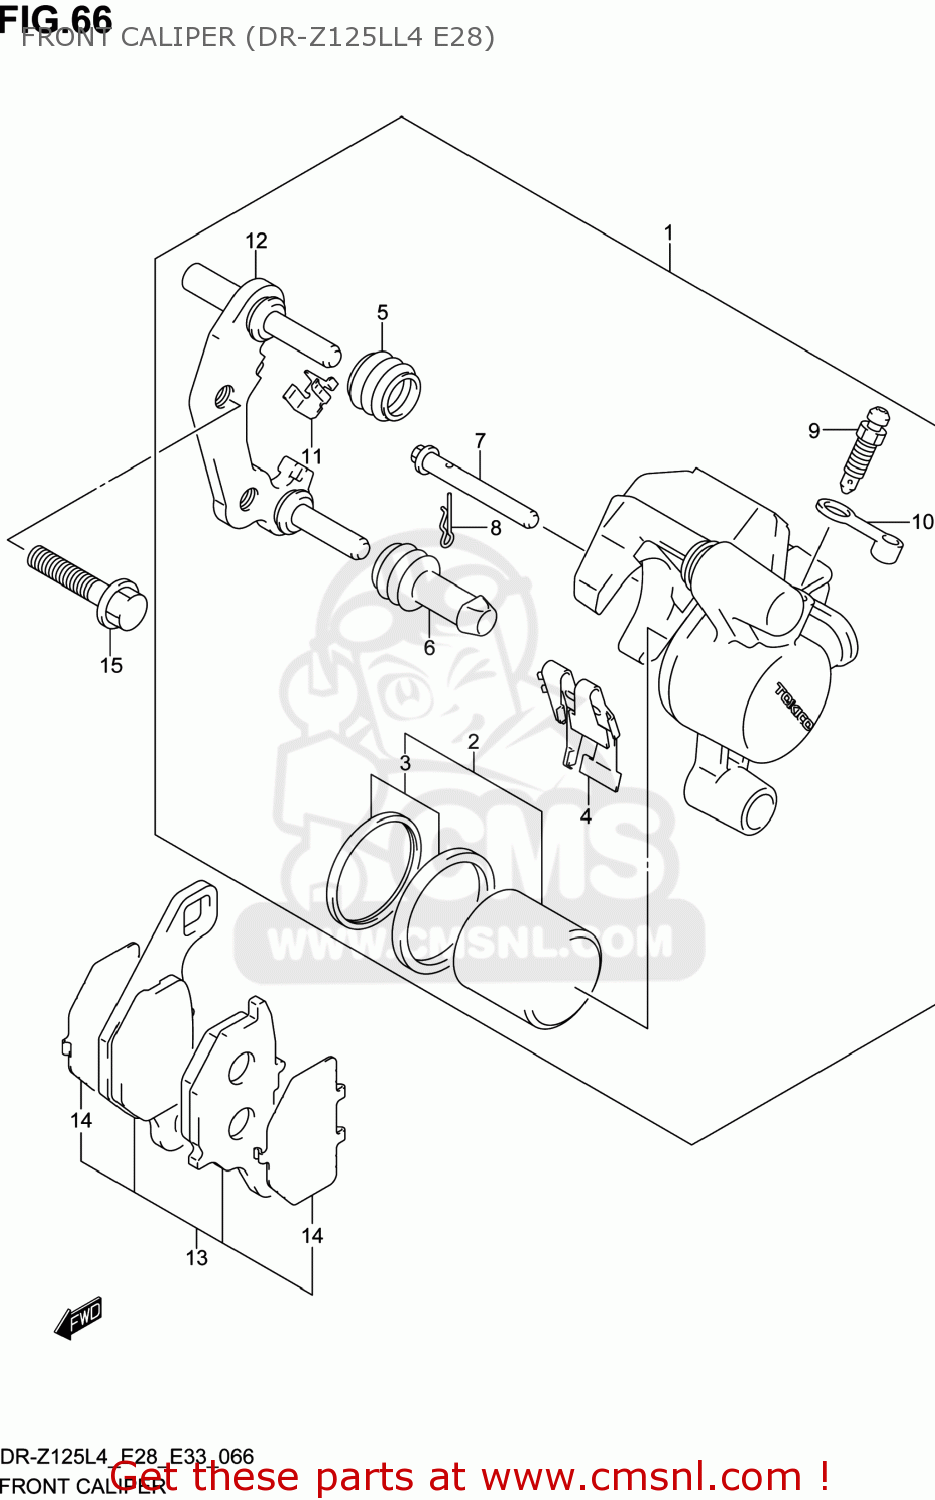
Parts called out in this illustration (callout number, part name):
1	CALIPER ASSY,FR,L
2	PISTON SET
3	SEAL SET,PISTON
4	SPRING,PAD
5	BOOT,AXLE
6	INSULATOR,AXLE
7	PIN,PAD
8	CLIP,PAD PIN
9	BLEEDER
10	CAP,BLEEDER
11	GUIDE,PAD
12	CARRIER,CALIPER,L
13	PAD & SHIM SET (NAS)
14	SHIM,PAD
15	BOLT
